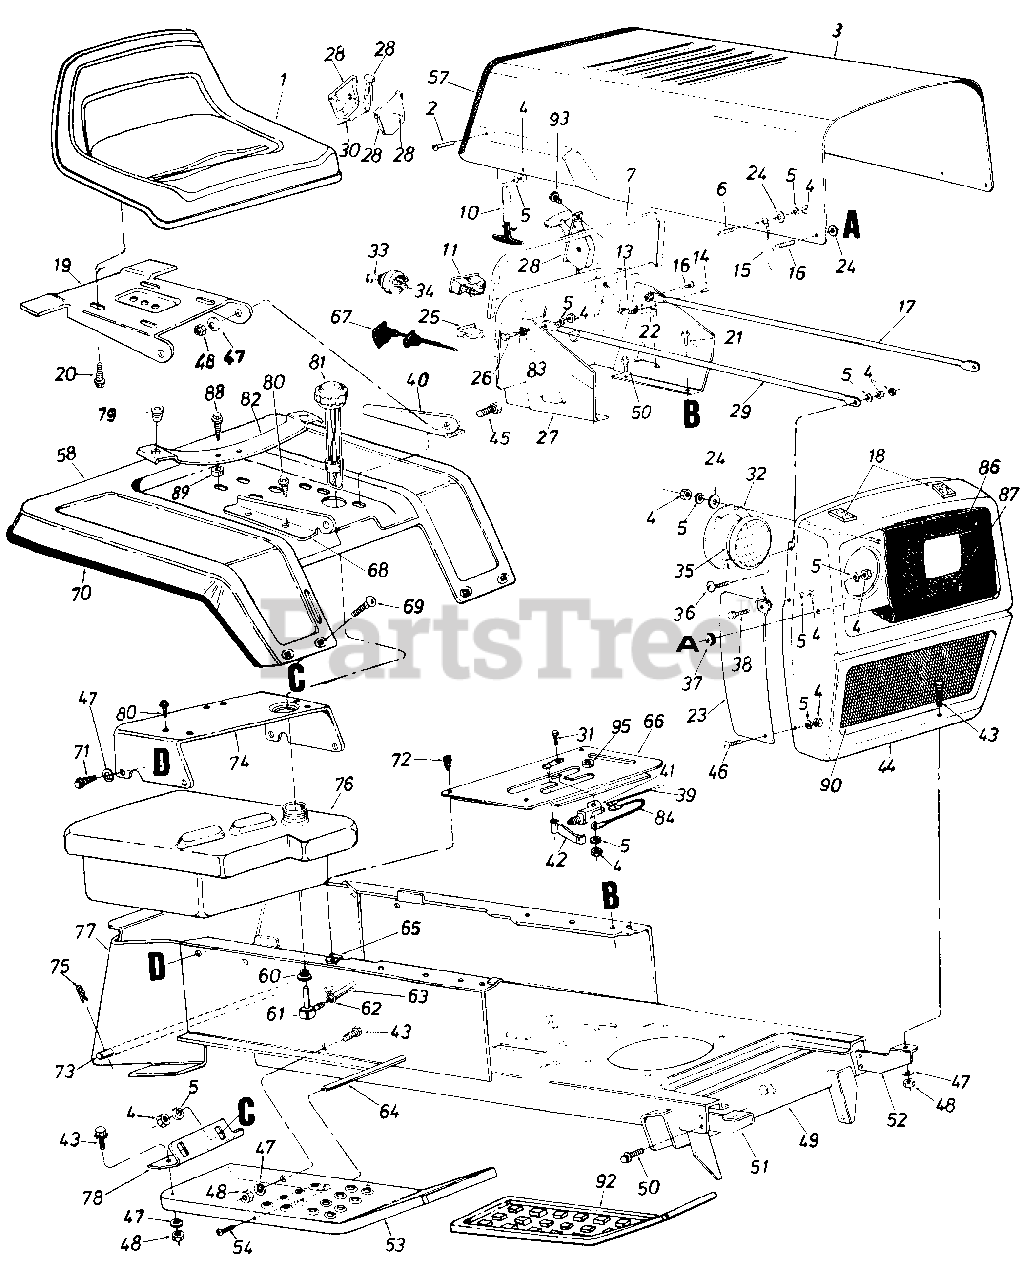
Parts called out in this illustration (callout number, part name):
1	Seat Assembly
2	Truss Mach. Scr. 1/4-20 x .50" Lg.*
3	Hood
4	Hex Nut 1/4-20 Thd.*
5	L-Wash. 1/4" Scr.*
6	Truss Mach. Scr. 1/4-20 x .50" Lg.*
7	Vinyl Molding Strip-29"
10	Hood Latch Ass'y.
11	Ammeter
13	Circuit Breaker 8 Amp.
14	Hex Tap Scr. #10 x .50" Lg.*
15	Hood Stop
16	Truss Mach Scr. 1/4-20 x .75" Lg .
17	Grille Positioning Rod
18	PVC Foam Strip 1/2 x 1.00" x 2.00" Lg.
19	Seat Pivot Brkt.
20	Hex Wash. Hd. AB-Tap Scr. 318 x .75" Lg .
21	Hex Thd. Rolling Scr. 1/4" x .50" Lg.
22	Speed Nut #10Z
23	Grille Side Panel-R.H.
24	Fl-Wash. 1/4" I.D.
25	Light Switch
26	Truss Hd. Scr. 1/4-20 x 1.00" Lg.*
27	Dash Panel Ass'y.
28	Throtle Control Box Comp.
29	Grille Positioning Rod
30	Throtle Control Cable
31	Hex Bolt 1/4-20 x .50" Lg.*
32	Head Lamp Retainer
33	Ignition Key
34	Ignition Switch
35	Head Lamp
36	Truss Machine Scr. 1/4-20 x .75" Lg.*
37	Rubber Wash. .50" I.D. x 1.00 O.D. x .25 Thk.
38	Truss Mach. Scr. 1/4-20 x .50" Lg.*
39	Reverse Lockout Wire Harness
40	Seat Bracket-L.H.
41	Safety Switch
42	Switch Actuator Spring Lever
43	Hex Scr. 5/16-18 x .75" Lg.*
44	Grille Ass'y.
45	Shld. Bolt .437" Dia.
46	Truss Mach. Scr. 1/4-20 x .50" Lg.*
47	L-Wash. 5/16" I.D.*
48	Hex Nut 5/16-18 Thd.*
49	Lower Frame Ass'y.
50	Hex Thd. Rolling Scr. 5/16" x .75" Lg.
51	Grille Mount Brkt.R.H.
52	Grille Mount Brkt.L.H.
53	Running Board-R.H.
54	Truss Mach. Scr. 5/16-18 x .75" Lg.*
57	Vinyl Moulding Strip-30"
60	Bushing
61	90ø Nipple
62	Hose Clamp 3/8"
63	Gas Line 46" Lg.
64	Running Board Rod
65	Speed Nut #10-24
66	Transmission Cover Ass'y.
67	Choke Control Comp.
68	Seat Bracket-R.H.
69	Carr. Bolt 1/4-20 x .50" Lg.
70	Trim Strip-81" Lg.
71	Hex Thd. Rolling Scr. 5/16-24 x .75" Lg.
72	Truss Hd. Scr. #10 x .50" Lg.
73	Hitch Rod
74	Seat Mounting Channel
75	Internal Coter Pin
76	Gas Tank
77	Hitch Plate
80	Hex Wash. Hd. Self-Tap Scr. 5/16-18 x .50" Lg.
81	Gas Gauge
82	Seat Spring
83	External Wash. 1/4" I.D,
84	Electric Wire
86	Headlight Bezel
87	Hex Wash. Hd. F-Tap Scr. #8-32 x .38" Lg.
88	Hex Self-Tap Scr. 5/16-18 x 1.25" Lg.
89	Spacer
90	Grille Screen
92	Foot Pad
93	Truss Mach. AB-Tap Scr. #10 x .50" Lg.
95	Snap Bushing
